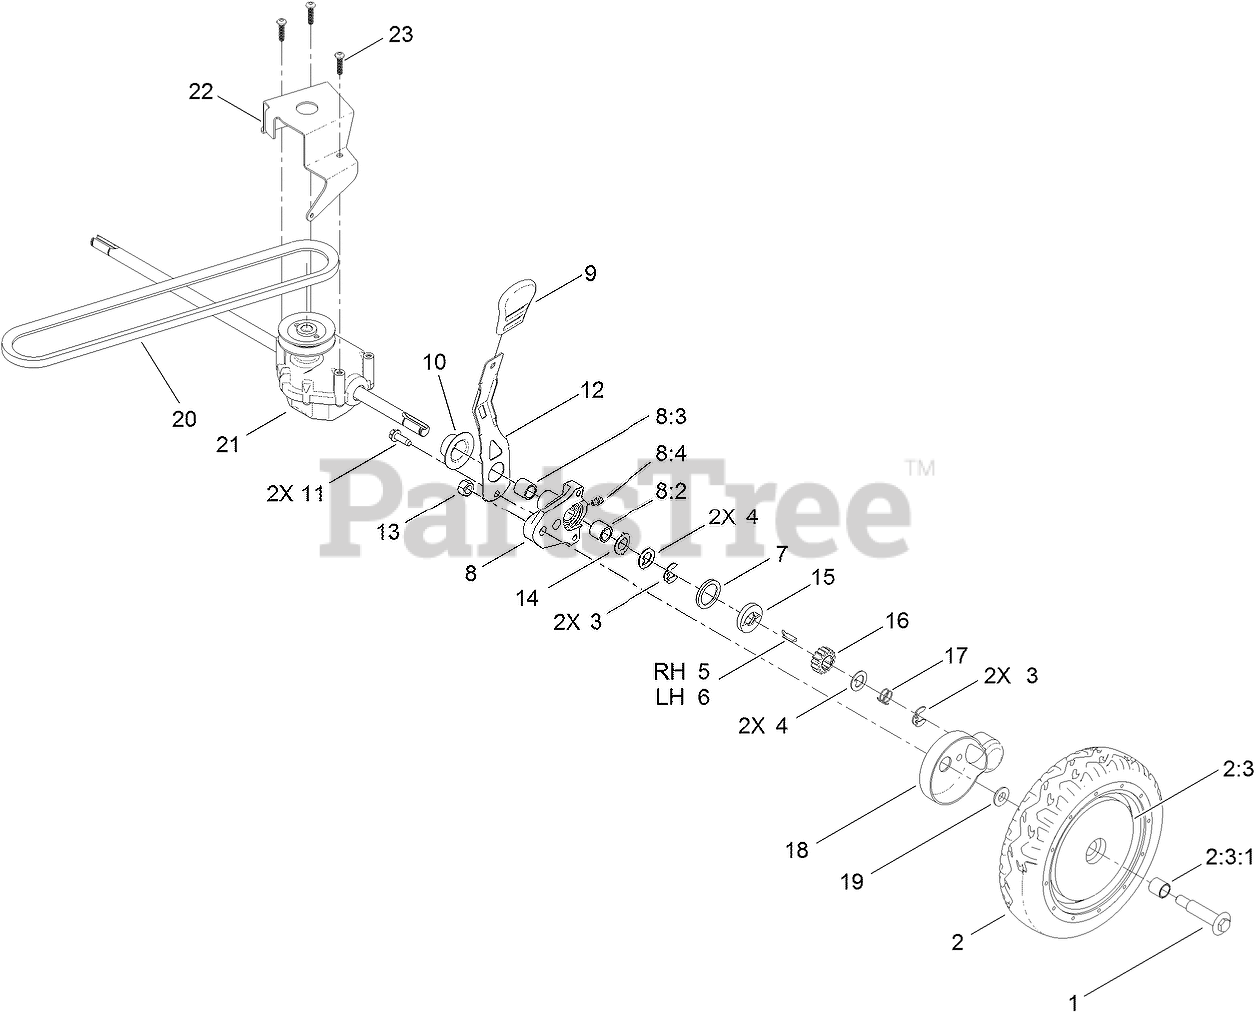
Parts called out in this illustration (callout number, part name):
1	BOLT-SHOULDER
2	WHEEL GEAR ASM
2:3	WHEEL ASM
2:3:1	BUSHING
3	RING-CLIP, LOCKING
4	WASHER-THRUST, KEYED
6	KEY-ROCKING, LH
7	RING-FRICTION
8	PIVOT ARM ASM
8:2	BUSHING
8:3	BUSHING
8:4	FITTING-GREASE
9	KNOB-HOC
10	CAP-END
11	SCREW-HWHTF
12	ARM-SPRING
14	WASHER-ARM, PIVOT
15	WASHER-CLUTCH
16	GEAR-PINION
17	SPRING-COMPRESSION
18	COVER-WHEEL
19	SPACER-COVER, WHEEL
20	V-BELT
21	TRANSMISSION ASM
22	BRACKET-TRANSMISSION
23	SCREW-PLASTITE
